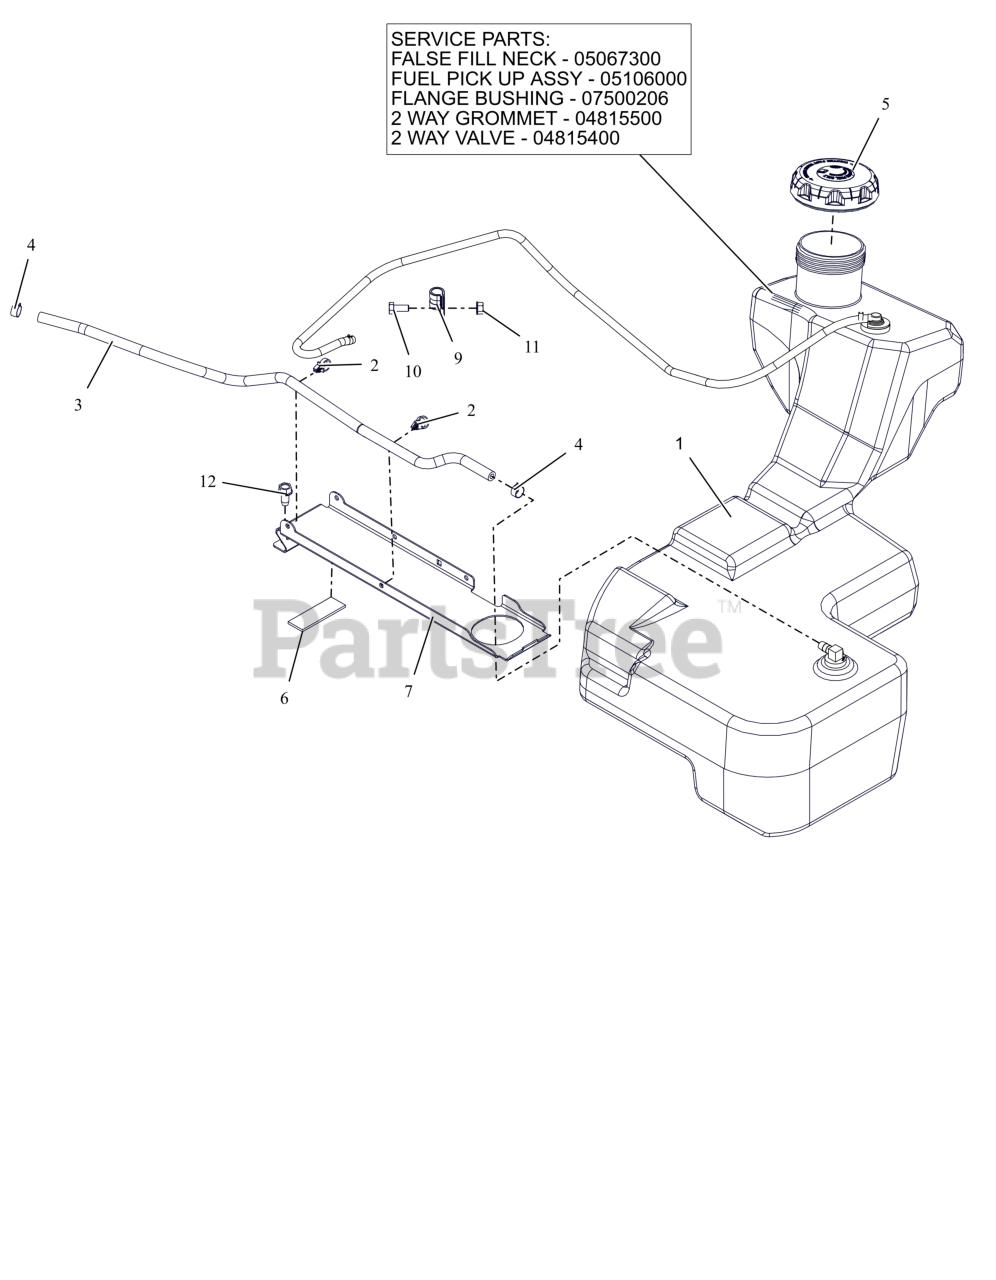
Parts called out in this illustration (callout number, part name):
1	ASM, FUEL TANK-HD
1	INSERT, FUEL NECK FALSE FILL
1	ASM, HD FUEL PICK-UP
1	BSHG-FLG .375X1.062X.625 NITR
1	GROMMET, 2-WAY
1	VALVE, 2-WAY
2	ROUTING CLIP (1/2" ID)
3	HOSE, .25 LOW-PERM BULK GAS
4	CLAMP, FUEL LINE
5	CAP, FUEL VENTIN AUTOLOCK
6	PAD,RBR 1.0"X3.0" W/ADHESIVE
7	BRKT, FUEL TANK HOLD DOWN
9	CLAMP, CUSHIONED STEEL
10	BLT,HEX .31-18X.75 G5 ZCC
11	NUT,LK-CTR-FLG .31-18 GF ZCC
12	SCR,TAP .375-16X.75 HWH TR ZCC
